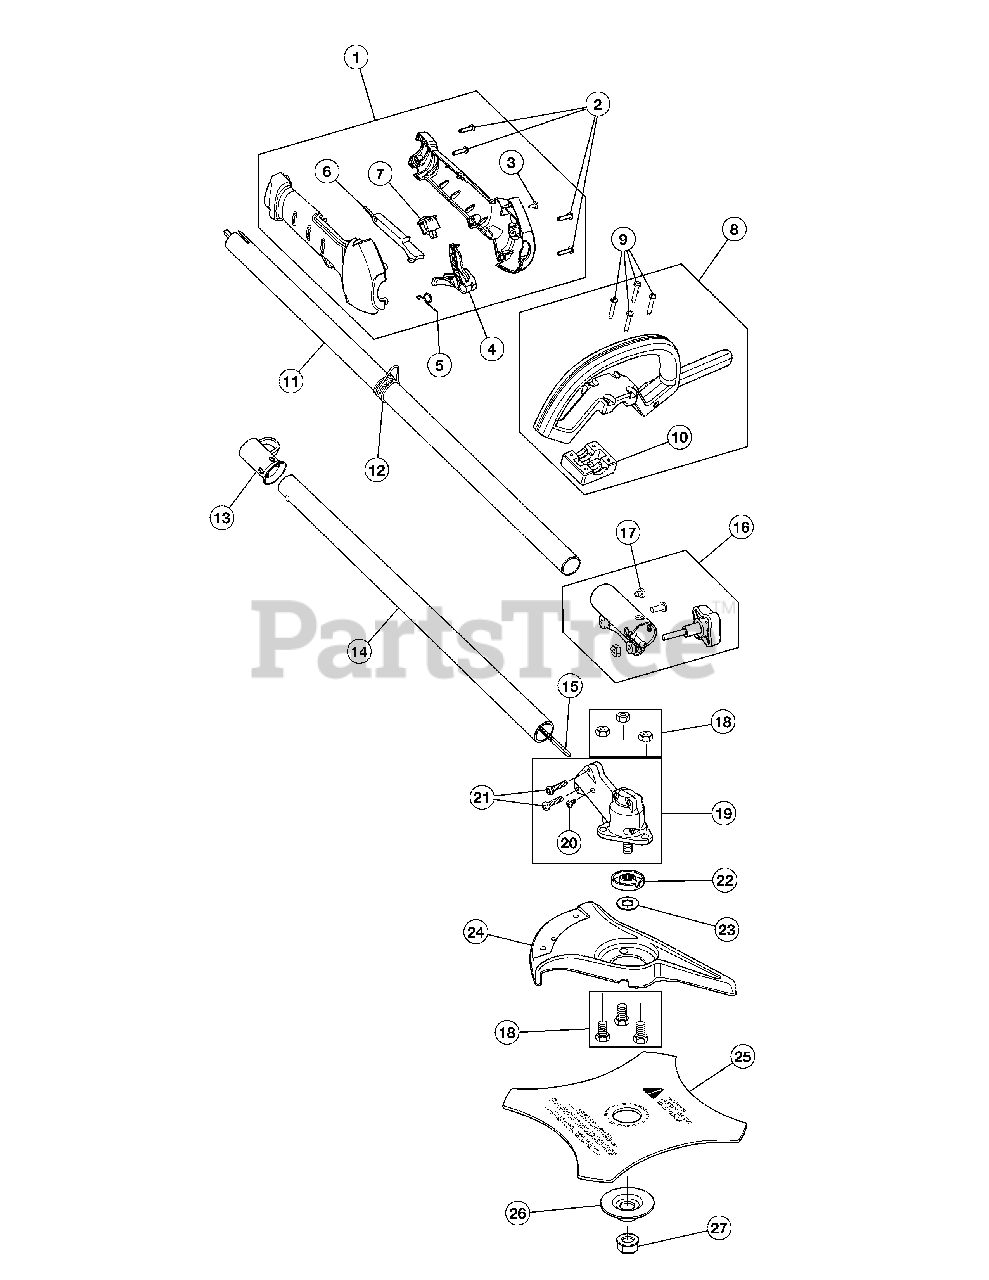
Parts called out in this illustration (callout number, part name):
1	Throttle Grip Assembly (Incl. 2 - 7)
3	Anti-Rotation Screw
4	Throttle Trigger
5	Throttle Trigger Spring
8	D-Handle Assembly (Incl. 9)
10	D-Handle Base
11	Upper Drive Shaft Assembly
12	Harness Clip
14	Lower Drive Shaft Housing Assembly
15	Lower Flexible Drive Shaft
16	Split Boom Coupler Assembly
18	Shield Mount Screw Assembly
19	2 Piece Gearbox Assembly
20	Anti-Rotation Screw
21	Gearbox Mounting Hardware
22	Blade Driver
24	Blade Shield/Shield Mount
25	4-Tooth Blade
26	Retaining Washer
